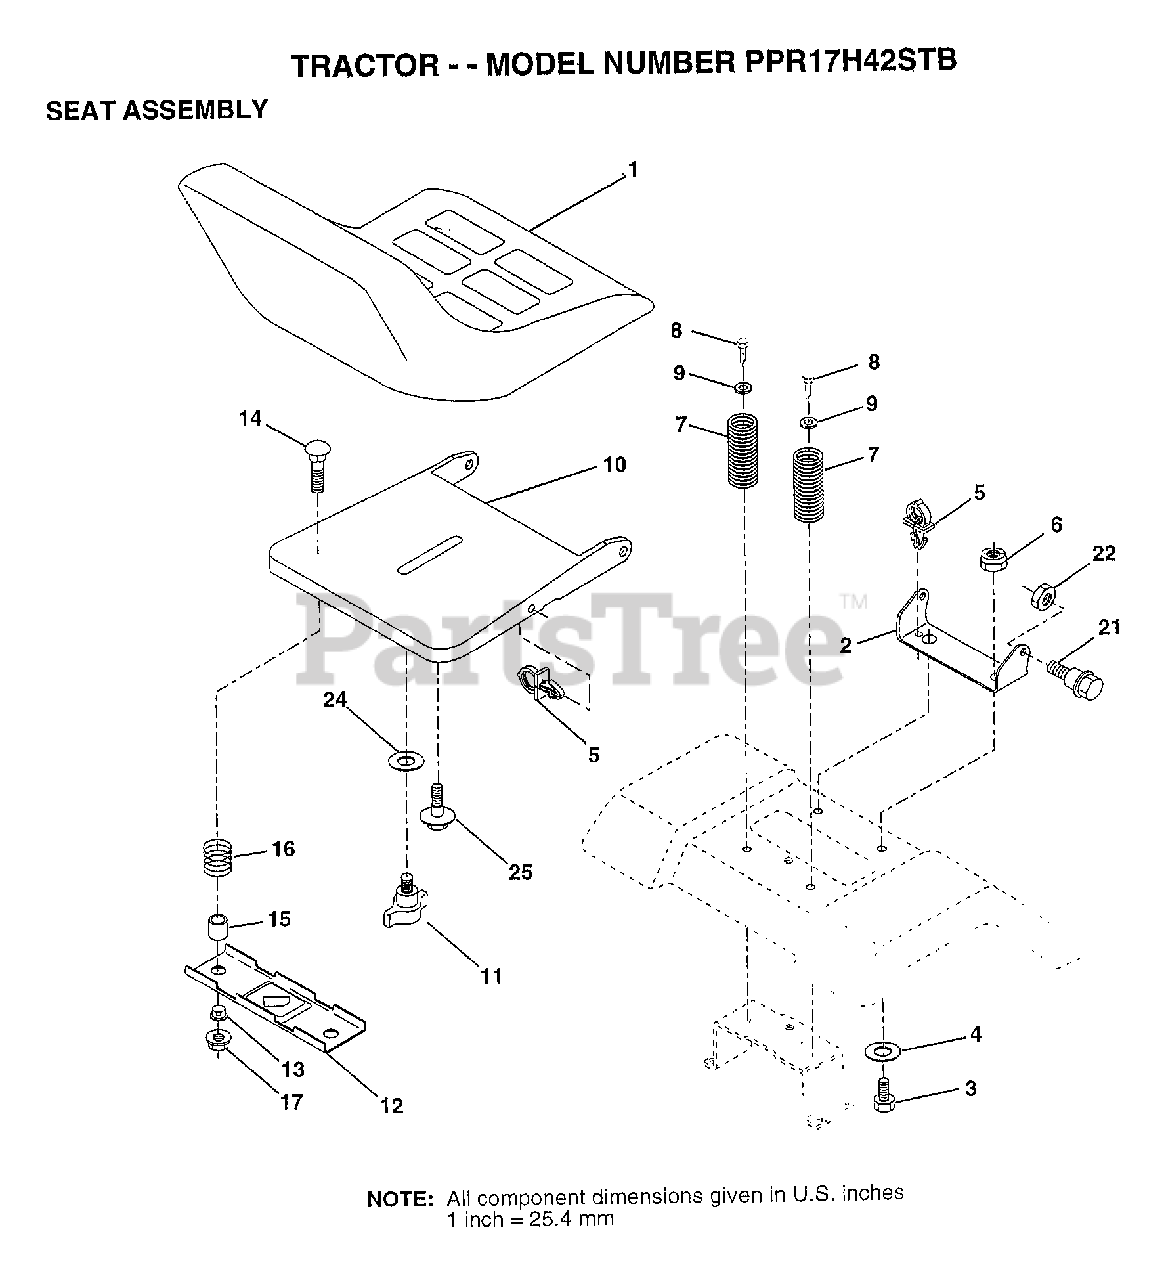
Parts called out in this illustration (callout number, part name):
1	SEAT.2400/1416.BK
2	BRACKET PVT SEAT
3	BOLT
4	WASHER PM
5	CLIP.PUSH-IN.HING
6	NUT
7	SPRING, COMPRESSION, SEAT
8	SCREW
9	WASHER
11	KNOB.SEAT.ADJ.WINGNUT
12	BRKT SWITCH
13	BUSHING
14	BOLT-RD HD SQ NK
15	SPLIT SPACER
16	SPRING
21	"BOLT,SHOULDER"
22	NUT
24	WASHER
25	"BOLT,SHOULDER"
